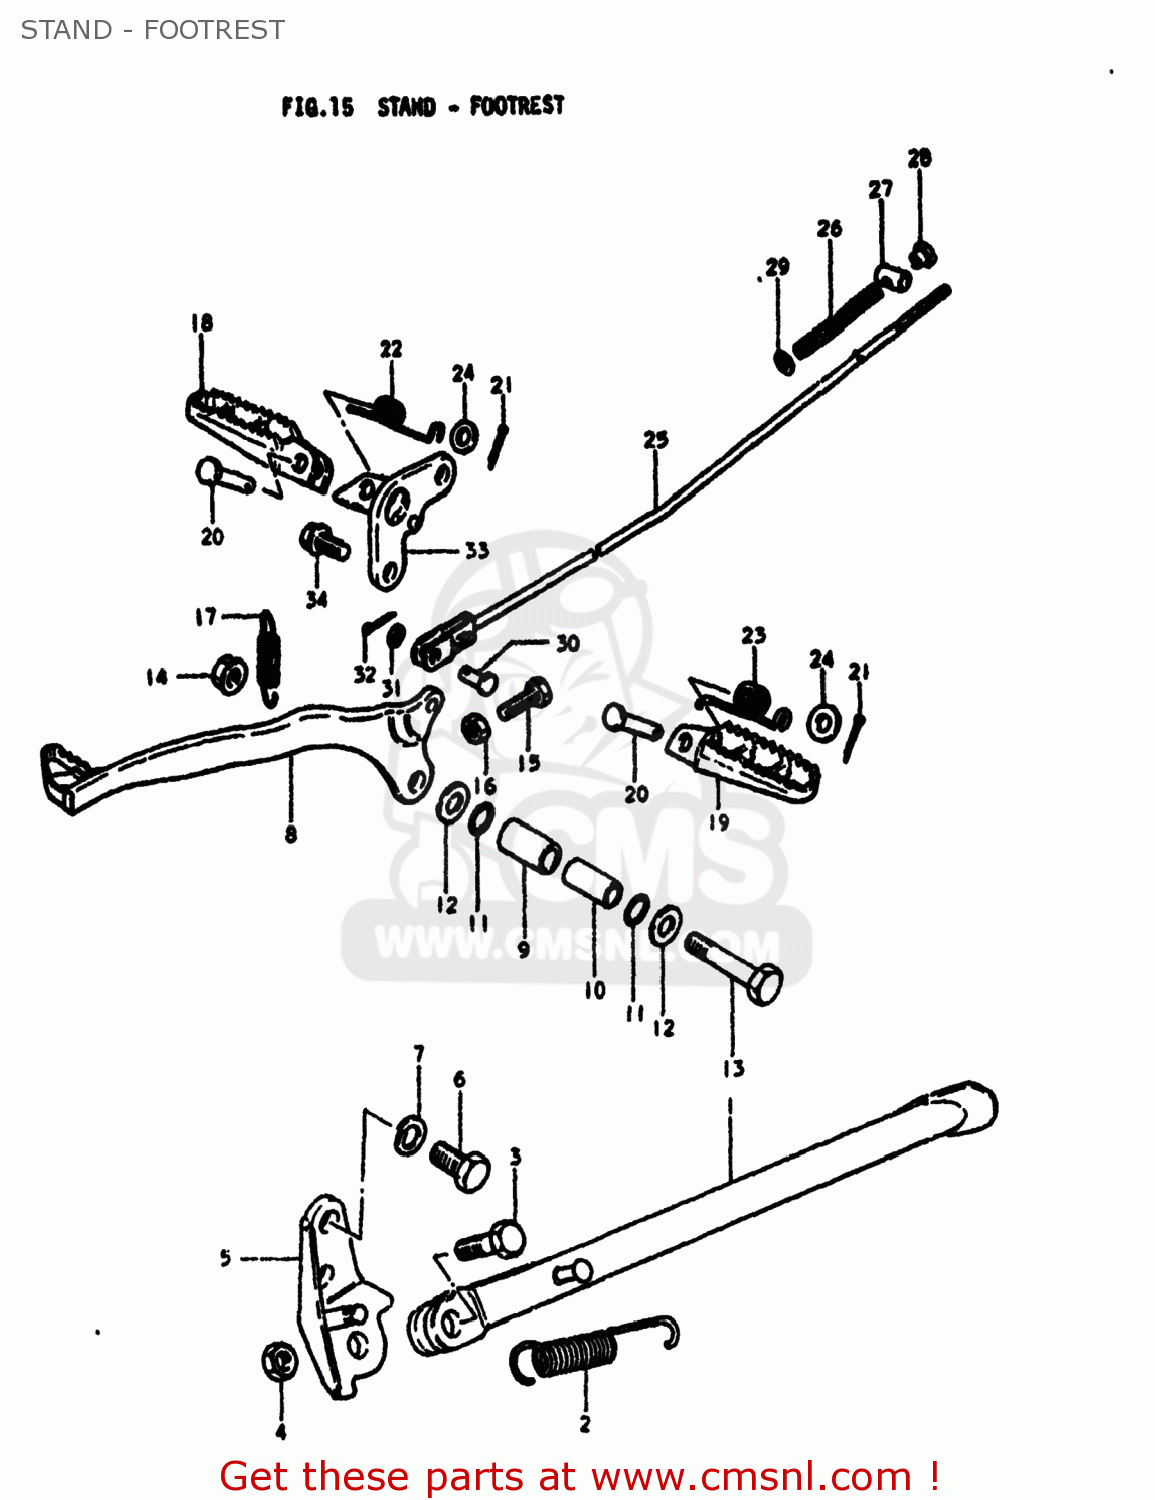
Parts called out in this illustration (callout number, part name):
1	STAND,SIDE
2	SPRING
3	BOLT(10X30)
4	NUT
5	BRACKET,PROP STAND
6	BOLT(10X19)
7	LOCK WASHER
8	PEDAL,BRAKE
9	BUSH
10	SPACER(10X14X32.2)
11	O RING(D:1.5,ID:13.8)
12	WASHER
13	BOLT
14	NUT
15	BOLT(6X23)
16	NUT
17	SPRING
18	RUBBER,FOOTREST
19	FOOTREST
20	PIN
21	PIN 20X20
22	SPRING
23	SPRING
24	WASHER
25	ROD ASSEMBLY,REAR BRAKE
26	SPRING
27	PIN
28	NUT
29	WASHER
30	PIN(L:13.5)
31	WASHER
32	PIN 20X20
33	HOLDER,FRONT FOOTREST,RIGHT
34	BOLT(10X20)
